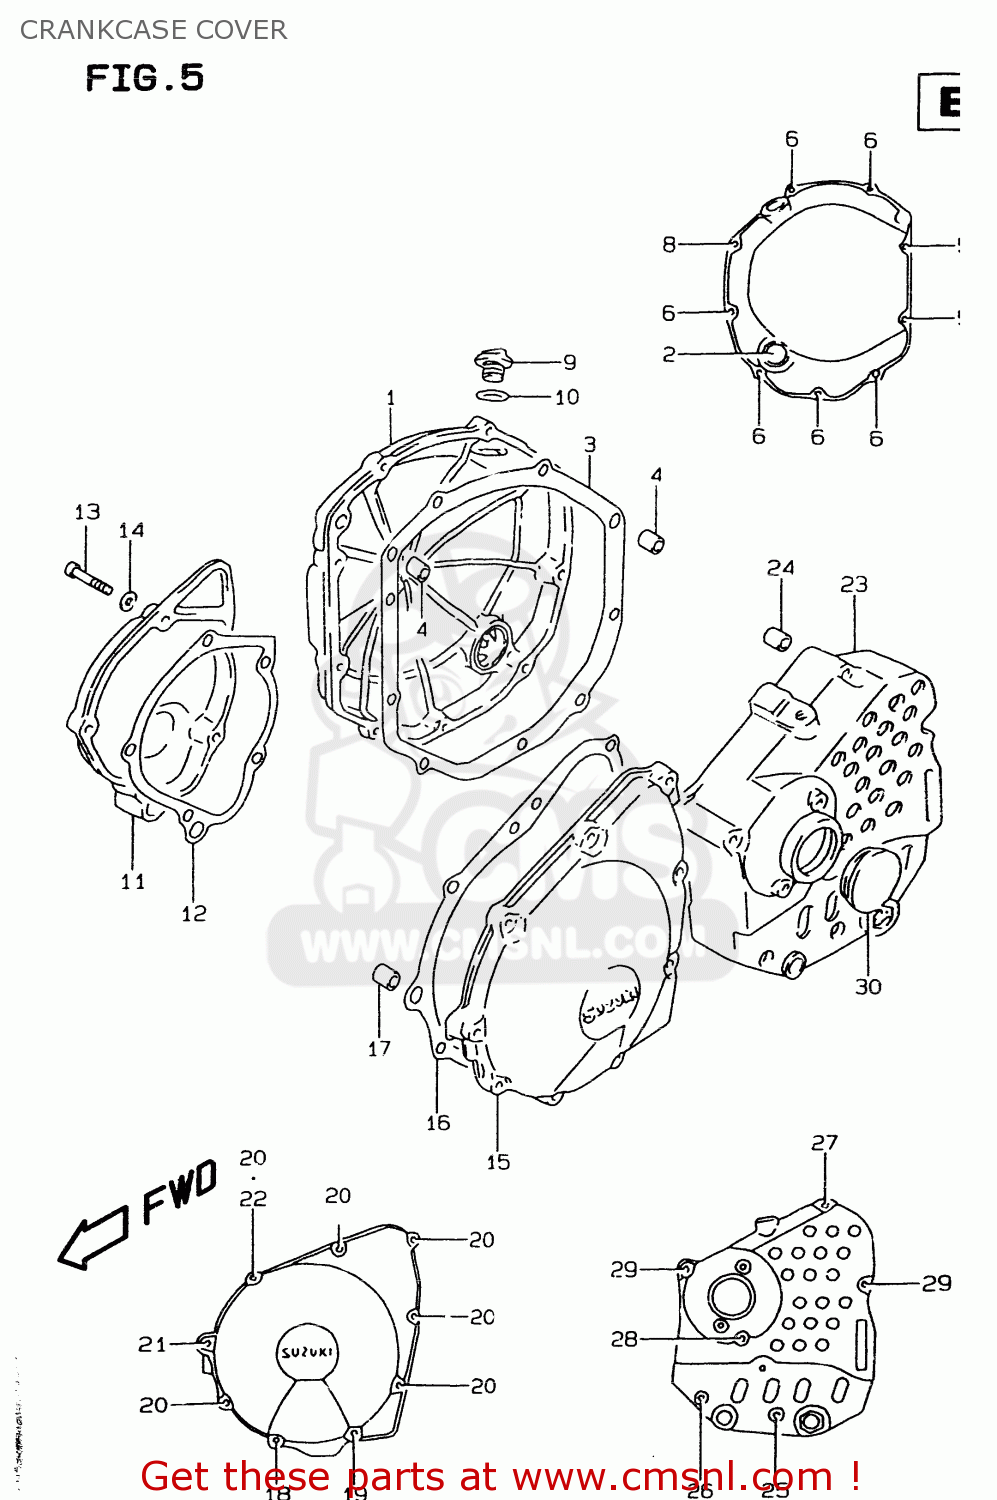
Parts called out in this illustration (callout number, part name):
1	COVER,CLUTCH
2	LENS,OIL LEVEL CHECK
3	GASKET,CL COVER (NAS)
4	PIN
5	GASKET(5.8X11X1.2) (NAS)
6	BOLT,CL.COVER
7	BOLT
8	BOLT
9	PLUG
10	O RING(D:3.1,ID:16.8)
11	COVER,SIGNAL GENERATOR
12	GASKET,SIGNAL GEN COVER (NAS)
13	BOLT(6X22)
14	GASKET(5.8X11X1.2) (NAS)
15	COVER,STARTER GEAR
16	GASKET,STARTER GEAR COVER (NAS)
17	PIN(8.4X11X20)
18	BOLT,OIL FILLE
19	BOLT,CRKCASE,R
20	BOLT,CL.COVER
21	BOLT
22	GASKET(5.8X11X1.2) (NAS)
23	COVER,ENGINE SPROCKET
24	PIN
25	BOLT
26	BOLT
27	BOLT,CL.COVER
28	BOLT
29	BOLT
30	CAP(OD:36)
